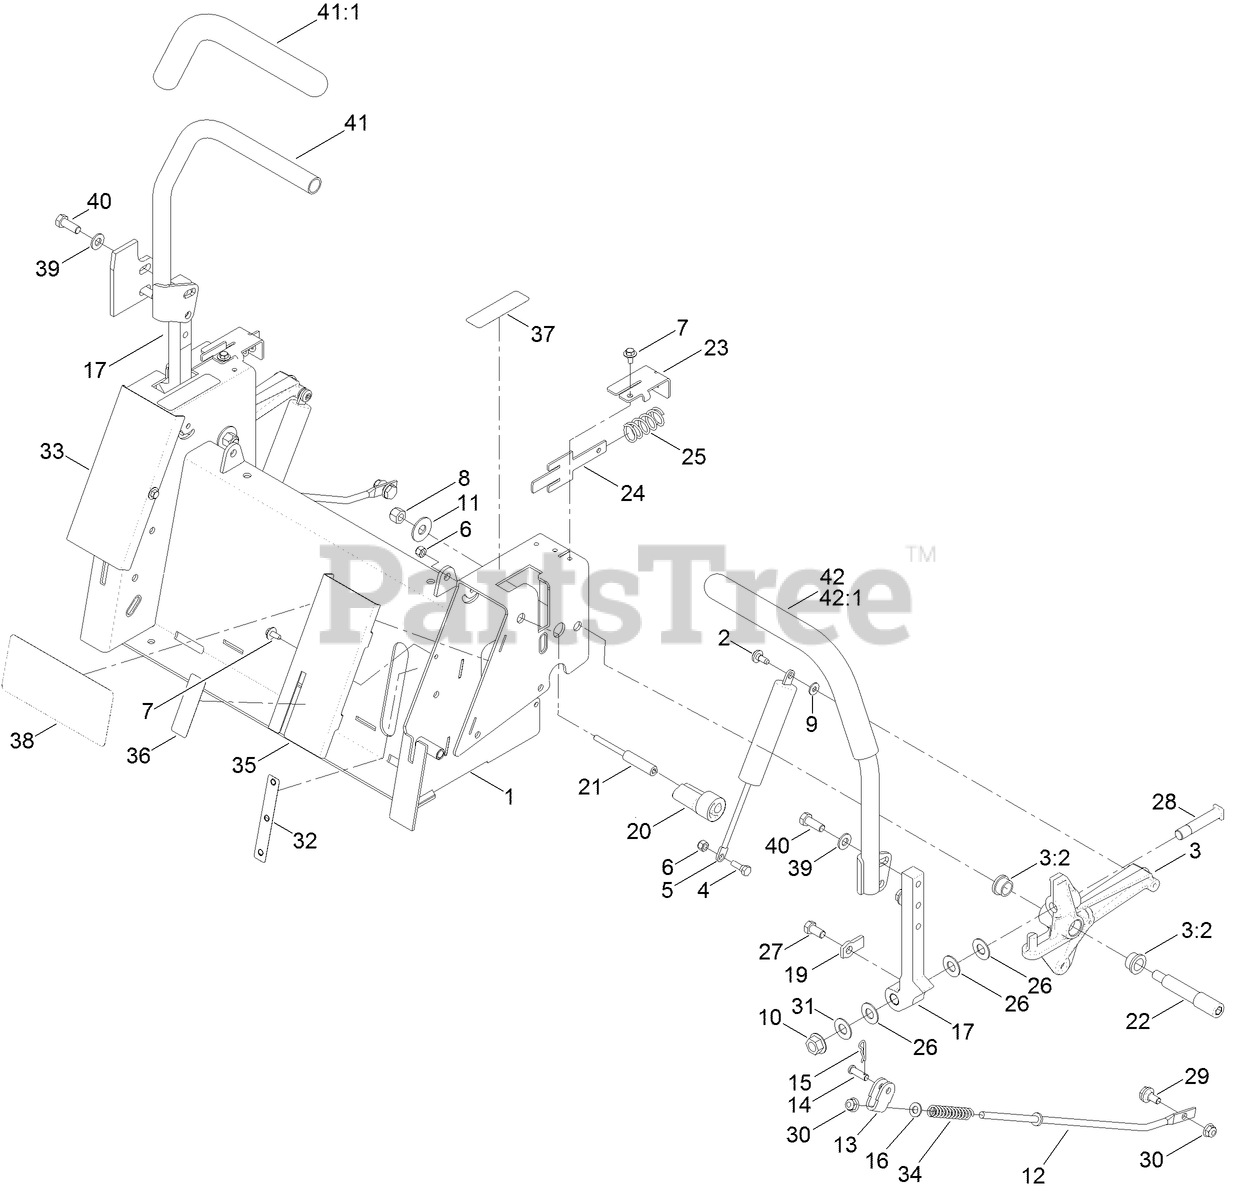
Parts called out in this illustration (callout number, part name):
1	BOX-CONTROL
2	SCREW-SHOULDER
3	ACTIVATOR ARM ASM
3:2	BUSHING
4	BOLT-SHOULDER
5	DAMPER
6	NUT-LOCK, NI
7	SCREW-HHFTF
8	NUT-LOCK, NI
9	WASHER
10	NUT-HF
11	WASHER-FLAT
12	ROD-CONTROL
13	BRACKET-CONTROL
14	PIN-CLEVIS
15	PIN-COTTER
16	WASHER-PLAIN
17	ARM-ACTUATOR, RH
19	TAB-STOP
20	ECCENTRIC
21	SCREW-ECCENTRIC
22	BOLT-SHOULDER
23	BRACKET-RETURN
24	PLATE-RETURN
25	SPRING-COMPRESSION
26	WASHER-PIVOT
27	SCREW-HH
28	BOLT-SHOULDER
29	BOLT-SHOULDER,HFH
30	NUT-HF, NI
31	WASHER-TEFLON
32	DECAL-FILL, FUEL
33	COVER-CONTROL, RH
34	SPRING-RETURN, NEUTRAL
35	COVER-CONTROL, LH
36	DECAL-BRAKE, PARKING
37	DECAL-CONTROL, MOTION
39	WASHER-FLAT
40	SCREW-HH
41	RH LEVER/GRIP ASM
41:1	GRIP-CONTROL, MOTION
42	LH LEVER/GRIP ASM
42:1	GRIP-CONTROL, MOTION
